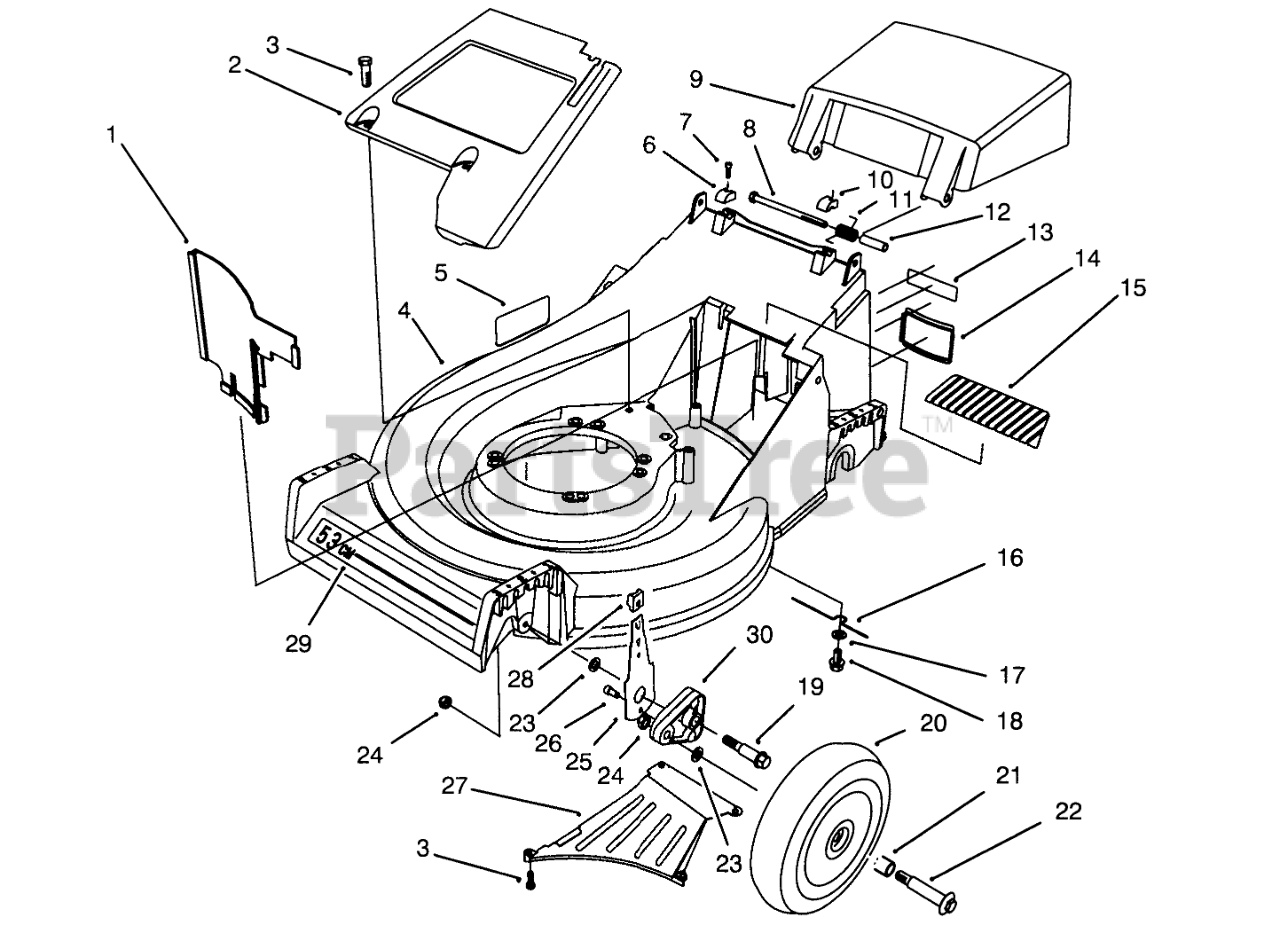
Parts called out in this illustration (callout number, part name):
1	PANEL-VERTICAL
2	PaneI-Screen
3	SCREW-HWHTF
4	Housing-53cm (Incl. Ref. #5 & 29)
5	DECAL - DIN/DANGER
6	CAP-HINGE BOLT, RH
7	SCREW-HSH
8	SCREW-HH
9	Door Discharge
10	CAP-HINGE BOLT, LH
11	SPRING-DOOR
12	SPACER-DOOR
13	DECAL FRENCH REGUL.
14	COVER-ACCESS
15	COVER-TOP
16	RETAINER-BELT
17	WASHER-FLAT
18	SCREW-HHFTF
19	BOLT-SHOULDER
20	Wheel & Tire Assembly (Incl. Ref. #21)
21	BUSHING
22	WHEEL BOLT
23	WASHER
24	NUT-LOCK
25	FRONT SPRING ARM ASM
26	SCREW-HSH, THREAD FORMING
27	Ramp-Discharge
28	KNOB-ARM
29	DECAL
30	ARM-PIVOT, FRONT
